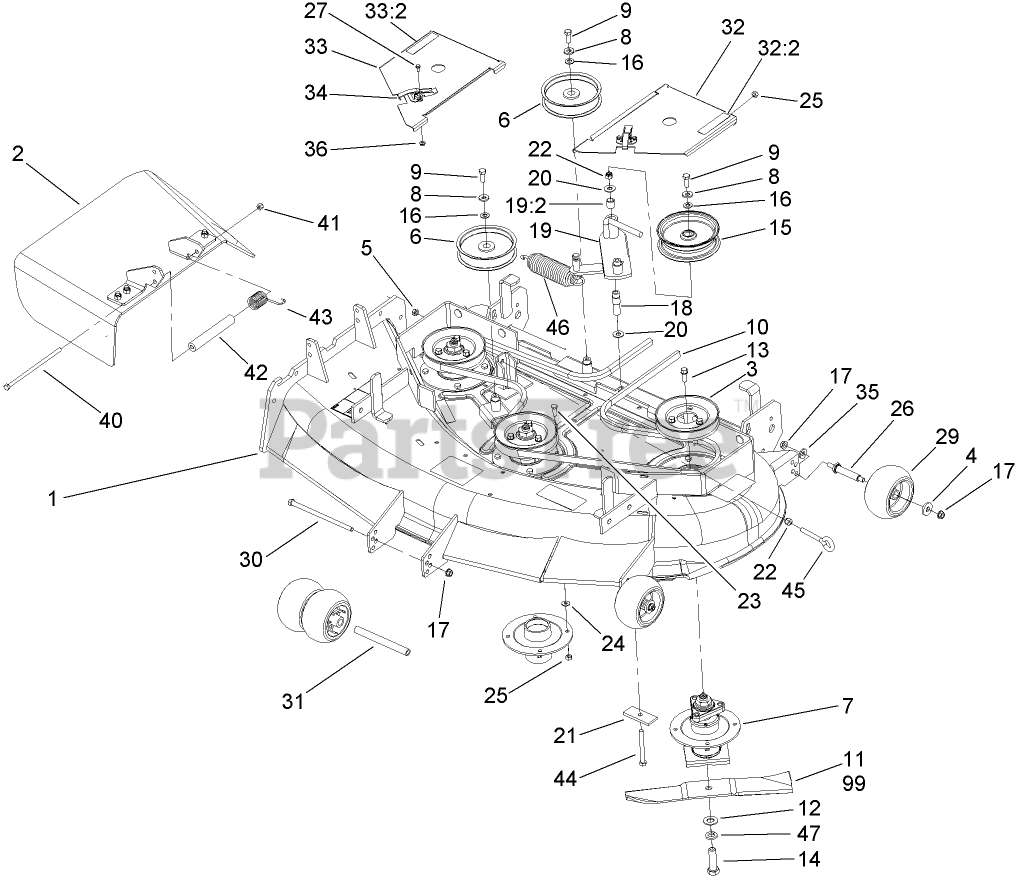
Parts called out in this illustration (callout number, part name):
1	DECK DECAL ASM
2	RUBBER DEFLECTOR ASM
3	PULLEY
4	WASHER
5	NUT-HEX
6	PULLEY-IDLER
7	SPINDLE HOUSING ASM
8	WASHER-BELLEVILLE
9	SCREW-HH
10	V-BELT, DRIVE
11	BLADE-RECYCLER
12	WASHER-FLAT
13	SCREW-HWH
14	SCREW-BLADE
15	PULLEY-IDLER, FLAT
16	WASHER-FLAT
17	NUT-HHF, WHIZ
18	BUSHING-PIVOT, IDLER
19	IDLER ARM ASM
19:2	SLEEVE-BEARING
20	WASHER-HARDENED
21	PLATE-RETAINER, BOLT
22	NUT-LOCK, NI
23	SCREW-HH
24	WASHER-FLAT
25	NUT-LOCK, CONE
26	SPACER
27	SCREW-HWH
29	ROLLER-SCALP, ANTI
30	SCREW-HH
31	SPACER-WHEEL
32	LH COVER ASM
32:2	DECAL-WARNING
33	RH COVER ASM
33:2	DECAL-WARNING
34	CLAMP-SLOTTED
35	WASHER-BELLEVILLE
36	NUT-LOCK, FLANGE
40	SCREW-HH
41	NUT-LOCK, NI
42	SPACER
43	SPRING-TORSION
44	SCREW-HH
45	BOLT-EYE
46	Spring-Extension
47	WASHER-LOCK
99	BLADE-ATOMIC
99	BLADE-LIFT, HIGH
